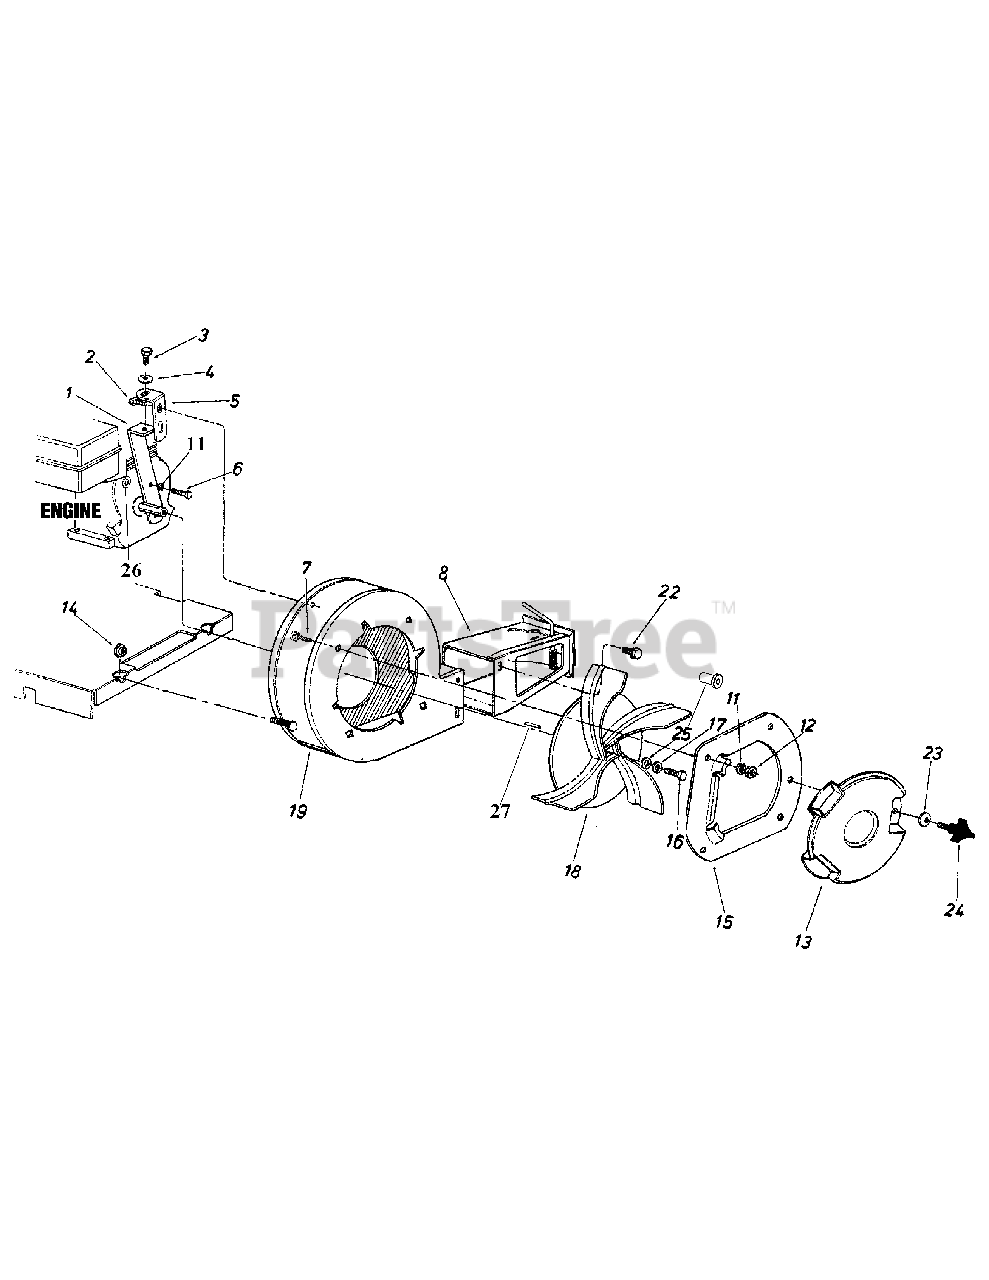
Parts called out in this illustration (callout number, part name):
3	Hex Screw 5/16-18 x .75
4	Special L-Washer 5/16" x .88 OD
6	Hex Locking Bolt 5/16-24 x 1.25 (Honda Engine)
7	Carriage Bolt 5/16-18 x .62
12	Hex Nut 5/16-18
13	Blower Guard
14	Hex Shoulder Nut .50"
16	Hex Bolt 3/8-24 x 2.75 (Honda Engine)
17	Lock Washer 3/8
23	Bell Washer .34 ID x .87 OD
24	Screw 5/16-18 x .75
25	Flat Washer
25	Impeller Hub (Honda Engine)
26	Engine Spacer 1.0OD x .34LG (Honda Engine)
27	Square Key, 3/16 (Honda Engine)
